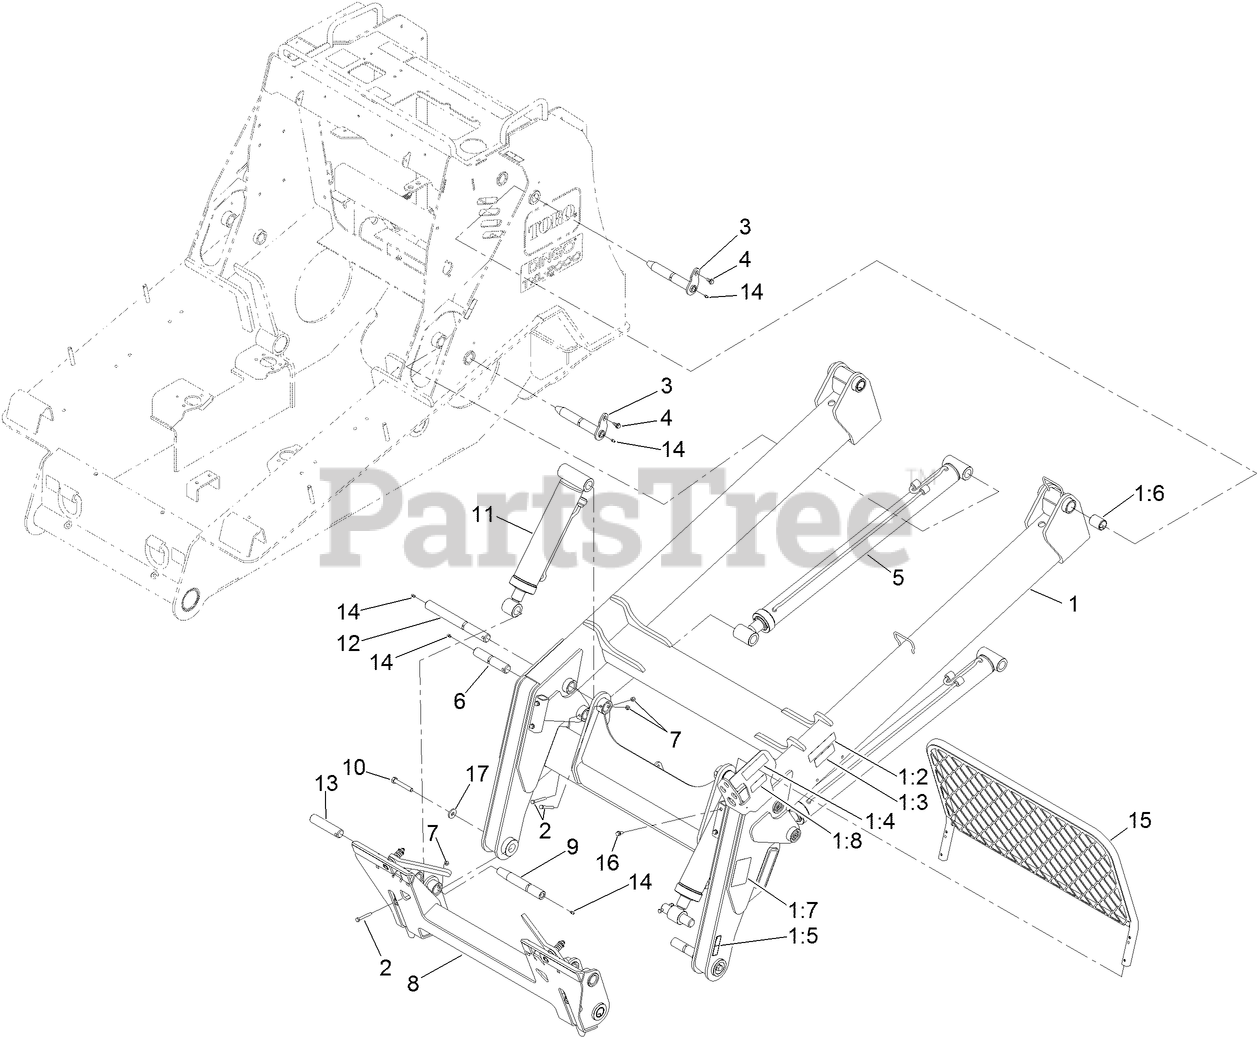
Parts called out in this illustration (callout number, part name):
1	LOADER ARM ASM
1:2	DECAL-WARNING, CRUSHING
1:3	DECAL-WARNING, BYSTANDERS
1:4	DECAL-CAUTION
1:5	DECAL-WARNING, PINCH POINT
1:6	BUSHING-SPRING
1:7	DECAL-WARNING, BUCKET
1:8	DECAL-WARNING, HYD PRESSURE
2	SCREW-HH
3	PIVOT PIN ASM
4	BOLT-SHOULDER
5	HYD CYL ASM
6	PIN-LINK
7	NUT-LOCK, NI
8	QTACH ASM
9	PIN-LINK, TAPER
10	SCREW-HH
11	HYD CYL ASM
12	PIN-LINK
13	PIN-LINK
14	FITTING-GREASE
15	SCREEN-DEBRIS
16	SCREW-HHF
17	WASHER
